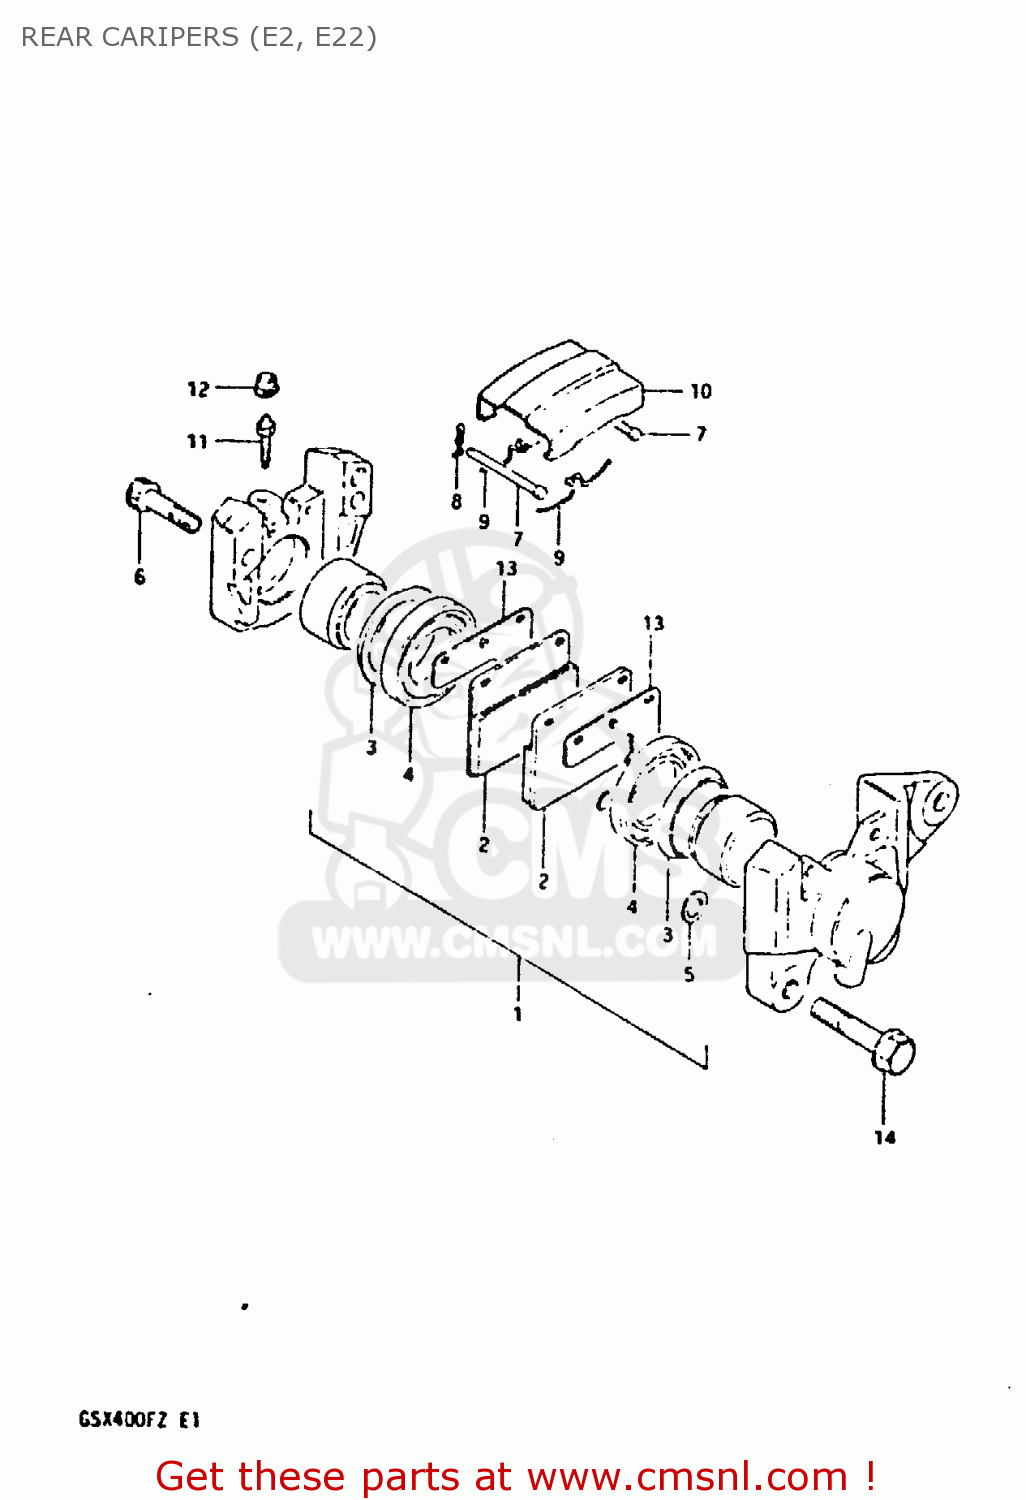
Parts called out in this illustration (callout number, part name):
1	PISTON SET
2	PAD,BRAKE
3	SEAL,PISTON
4	BOOT,PISTON
5	SEAL,JOINT
6	BOLT,CALIPER HOUSING
7	PIN,PAD
8	CLIP,PAD PIN
9	SPRING
10	COVER,DUST
11	BLEEDER
12	CAP,BREATHER
13	SHIM,RR CALIPER
14	BOLT
